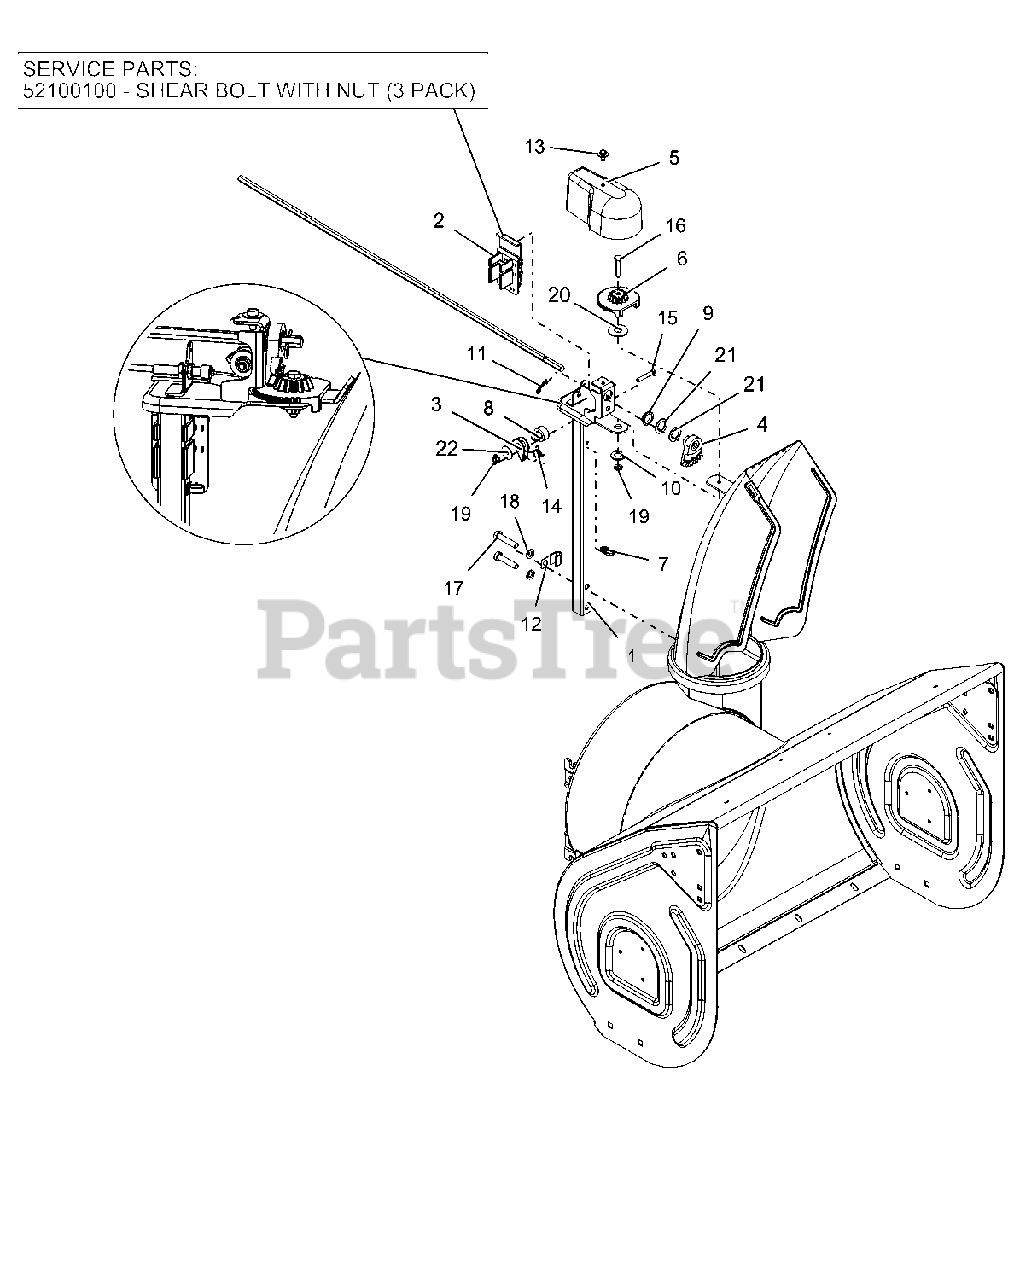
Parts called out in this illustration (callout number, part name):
1	PEDESTAL, CHUTE - QUICK STICK
2	SHEAR BOLT SERVICE ASSEMBLY
2	HOLDER W LARGE SHEAR BOLT /NUT
3	ARM, LOCKING
4	GEAR, CHUTE-ACTUATION
5	COVER, CHUTE GEAR
6	GEAR, CHUTE
7	CLIP, CABLE GUIDE
8	BUSHING, LOCK ARM
9	BUSHING, POLYLINER-.75 SNAPIN
10	BSHG-FLG .265X.477X.375X1.00
11	PIN-HAIR INT .08X.18X1.18 YWZC
12	J-CLAMP
13	SCR-TAP .25-20X.50 LGHWH TR YZ
14	SG-TORS
15	@BLT-RDHDSQNK .25-20X1.50 G5YZ
16	@BLT-HEX .25-20X1.50 GR5 YWZC
17	@BLT-HEX .38-16X1.75 GR5 YWZC
18	@WSHR-LK .38X.094 REG YWZC
19	@NUT-LK-CTR-FLG .25-20 YWZC
20	WSHR-FLT-NYL .515X1.375X.093
21	WSHR-FL-STL.754X1.125X.062YWZC
22	WSHR-FL-STL .281X1.000X.063
